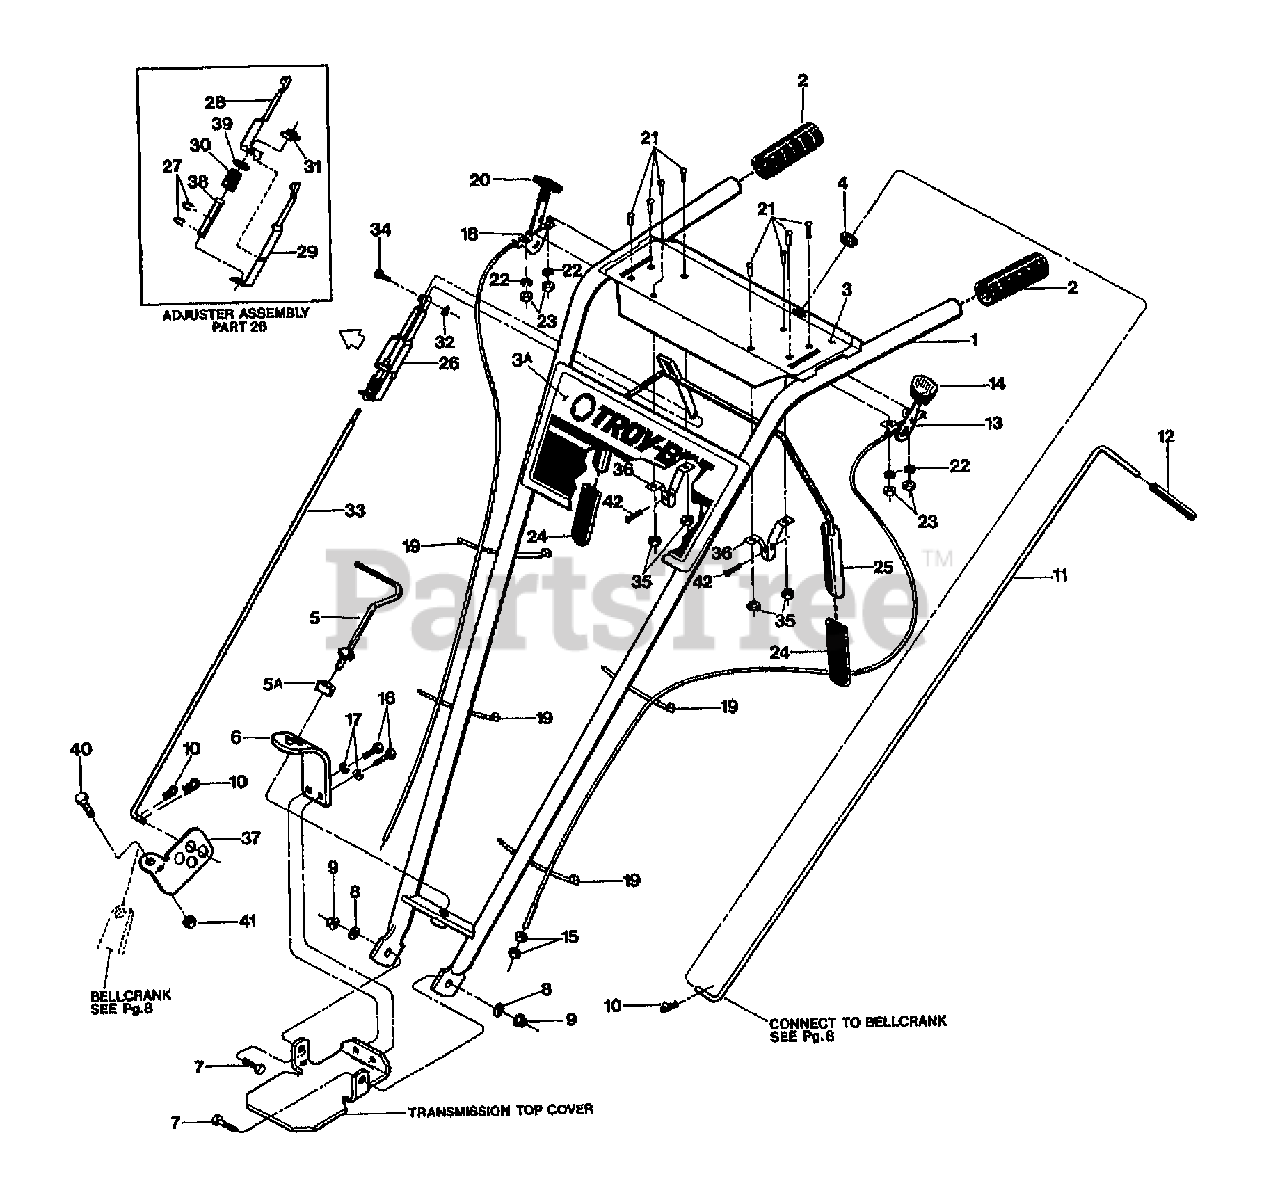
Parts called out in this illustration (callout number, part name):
1	ASSM-HANDLEBAR W/GRIPS (INCL. 2,3,3A,4)
2	GRIP-H/BAR SMOOTH
3	DECAL-CONTROL PANEL
3A	DECAL-GRAPHICS PANEL ECONO (NAME & LOGO)
4	BUSHING-NYLON (PART OF OPERATOR CONTROL PANEL)
5	ASSM-STUD H/B
5A	WASHER-1.0X.38X.375
6	PLATE-HANDLEBAR ADJUST
7	SCR-HH 3/8-16X1.0 G5 ZP
8	WASHER-FLAT 3/8 SAE (HANDLEBAR ATTACHMENT)
9	NUT-LOCK 3/8-16 NYLON ZP (HANDLEBAR ATTACHMENT)
10	PIN-CLIP .08
11	ROD-REV W/GRIP OPC - COMPLETE (INCL. #9198)
12	GRIP-CONTROL ROD
13	CABLE-WHEEL CLUTCH OPC (INCL. 14,15,19,21-23)
14	KNOB-WHEEL DRIVE CABLE
15	NUT-HEX 5/16-24
16	SCR-HH 3/8-16X.75 G5 ZP
17	WASHER-LK .375 @ DEPL
18	CABLE-THROTTLE ECONO OPC (INCL. 20)
19	TIE-RED(PLASTIC) TO SECURE CABLES TO HANDLEBAR
20	KNOB-THROTTLE CABLE
21	SCR-RH M10-32X.5 MACH
22	WASHER-LK M10
23	NUT-HH M10-32X.125
24	GRIP-PADDLE SM FRAME OPC
25	BAIL W/GRIPS OPC (INCL. TWO GRIPS, #24)
26	ASSM-ADJUSTMENT OPC (INCL. 27-30,38-39)
27	RING-KLIP .500 ZINC
28	ADJUSTER-RT SIDE OPC
29	ADJUSTER-LT SIDE OPC
30	SPRING-ADJUSTER OPC
31	WELDNUT 5/16-18
32	RING-KLIP .188 DIA
33	ROD-CONTROL OPC
34	ASSM-PIN & CLIP (SMALL FRAME)
35	NUT W/LKWASHER #10-32 ZP
36	BRACKET-BAIL OPC
37	SWIVEL-SMALL FRAME
38	BUSHING-.5X.334X2.88
39	WASHER-.75X.51X.06 ZP
40	SCR-HH 1/4-20X.75 G5 ZP
41	NUT-LK 1/4-20
42	SCR-HWH 1/4-20 X .5 STH
